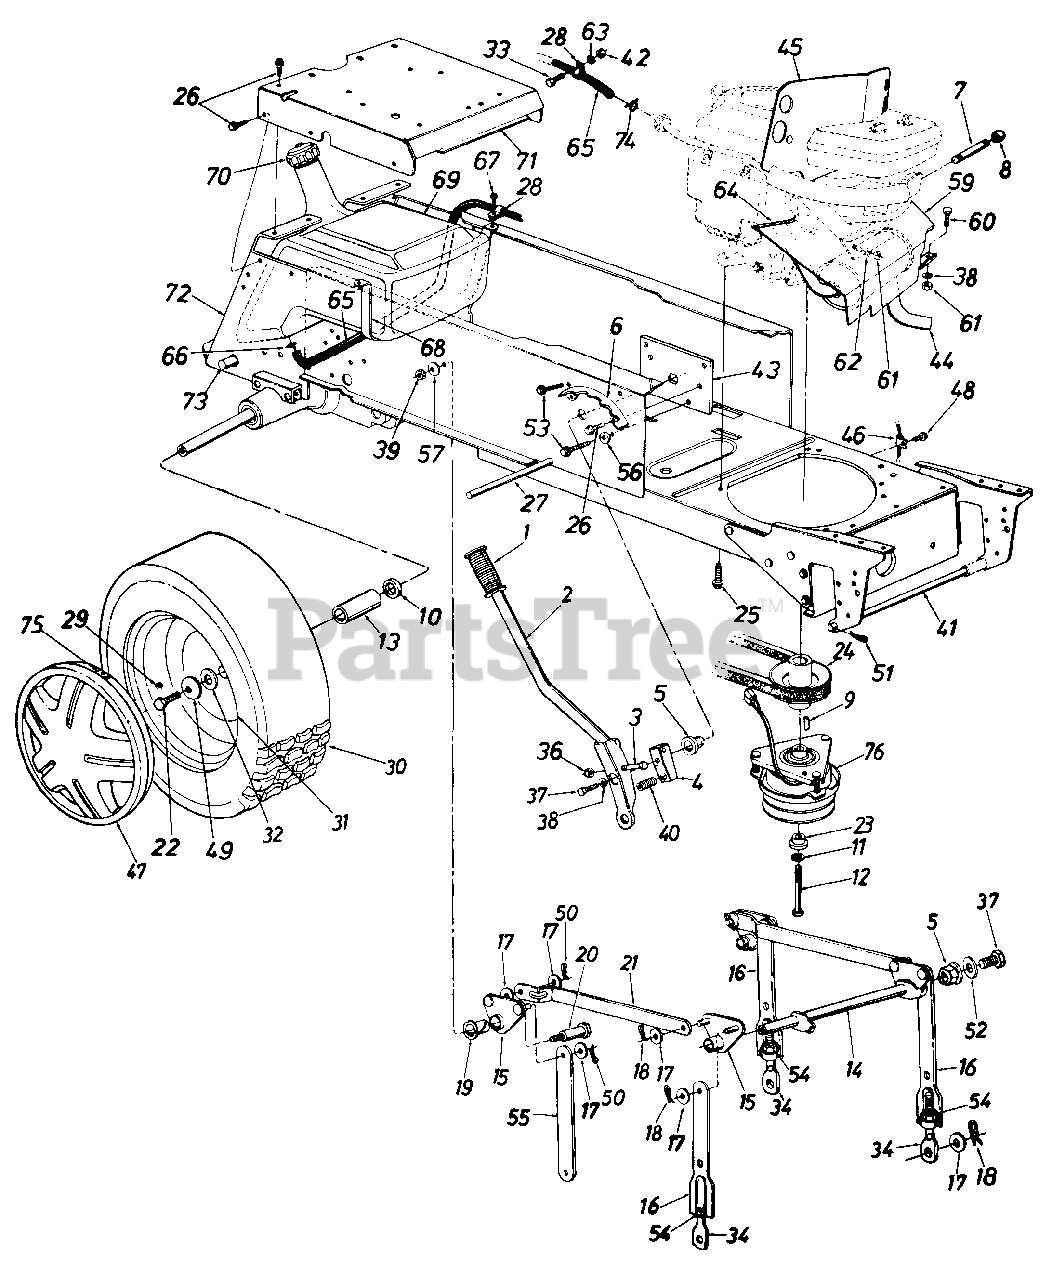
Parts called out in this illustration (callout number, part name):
1	Grip
2	Lift Handle Ass'y.
3	Hex Bolt 5/16-18 x 1.5" Lg.*
4	Lift Shaft Drive
5	Plastic Hex Brg. 518" I.D.
8	Pipe Cap 3/8-18 Npt.
9	Sq. Key 1/4" x 1/4" x 1.50" Lg.
10	Fl-Wash. .76" I.D. x 1.49" O.D.
11	L-Wash. 7/16" I.D.*
12	Hex Bolt 7/16-20 x 3.75" Lg.
13	Sleeve .75" I.D. x 1.0" O.D.
14	Lift Shaft Ass'y.
15	Lift Pivot Brkt. Ass'y.
17	Fl-Wash. 1/2" I.D. x 1.00" O.D. x .090"
18	Hairpin Cotter
19	Nyliner 5/8" I.D. x .88" Lg.
20	Shld. Bolt 5/8" Dia. x .96" Lg. 3/8-16
23	Shoulder Spacer
24	Engine Pulley
25	Hex Wash. Hd. Scr. 3/8-16 x 1.25" Lg.
26	Hex Thd. Rolling Scr. 5/16-18 x.75" Lg.
27	Running Board Rod
28	Clamp
29	Air Valve
30	Rear Wheel Ass'y. Comp.
31	Rear Wheel Rim Only
32	Flat Washer .34" I.D.
33	Hex Bolt 1/4-20 x .62" Lg.
34	Eye Bolt Adj. Link 1/2-13 Thd.
36	Hex Cent. L-Nut 5/16-18 Thd.
37	Hex Scr. 5/16-24 x .62" Lg.*
38	L-Wash. 5/16" I.D.*
39	Hex Top L-Nut 3/8-16 Thd.
40	Compression Spring
41	Deck Connecting Rod
42	Hex Nut 1/4-20 Thd.
45	Heat Shield
46	Mounting Clamp
47	Hubcap
48	Hex Wash. Hd. TT-Tap Scr. 1/4-20 x .5" Lg.
49	Bell-Wash..39" I.D.
50	Cotter Pin .09 Dia. x 1.0" Lg.
51	Int. Cotter Pin
52	Flat Wash. .34" I.D. x 1.12" O.D. x .125"
53	Hex Wash. Hd. AB-Tap Scr. 5/16-24 x .5" Lg.
54	Hex Nut 1/2-13 Thd.
56	Fl-Wash. 344n I.D.
57	Bell-Wash. .4" I.D. x 1.13" O.D.
59	Front Heat Shield
60	Hex Bolt 5/16-18 x .75" Lg.
61	Hex Nut 5/16-18 Thd.
62	L-Wash. 5/16" I.D.
63	L-Wash. 1/4" I.D.
64	Trim Strip 10" Lg.
65	Fuel Line 50" Lg.
66	Hose Clamp
67	Hex AB-Tap Scr. 1/4 x .62" Lg.
68	Fuel Tank Strap
69	Gas Tank
70	Gas Gauge
71	Seat Plate
74	Hose Clamp
75	Spring Clip
76	Electric Clutch
